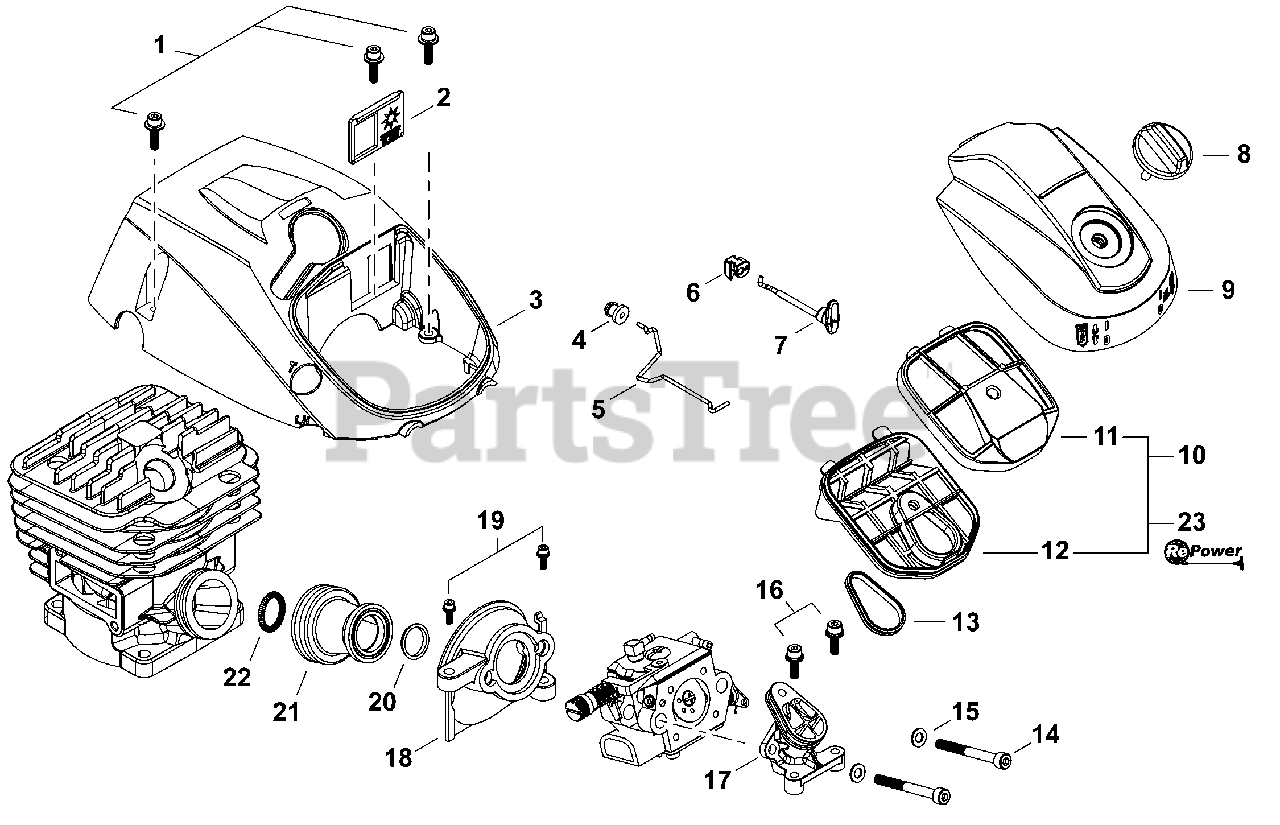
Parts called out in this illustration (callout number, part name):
1	BOLT M4×16
2	PLATE, SHUTTER
3	COVER, ENGINE
4	GROMMET, THROTTLE ROD
5	ROD, THROTTLE
6	GROMMET, CHOKE
7	ROD, CHOKE
8	THUMBSCREW
9	COVER, AIR FILTER
10	AIR FILTER ASSY, FLOCKED
11	FILTER, FLOCKED UPPER AIR
12	FILTER, FLOCKED LOWER AIR
14	BOLT M5×48
15	WASHER, FLAT 5.5×10×0.8
16	BOLT M4×16
17	ADAPTOR, AIR FILTER
18	INSULATOR, INTAKE
19	BOLT M4×16
20	COLLAR 16
21	BELLOWS, INTAKE
22	SPRING, TENSION
23	TUNE-UP KIT - REPOWER
